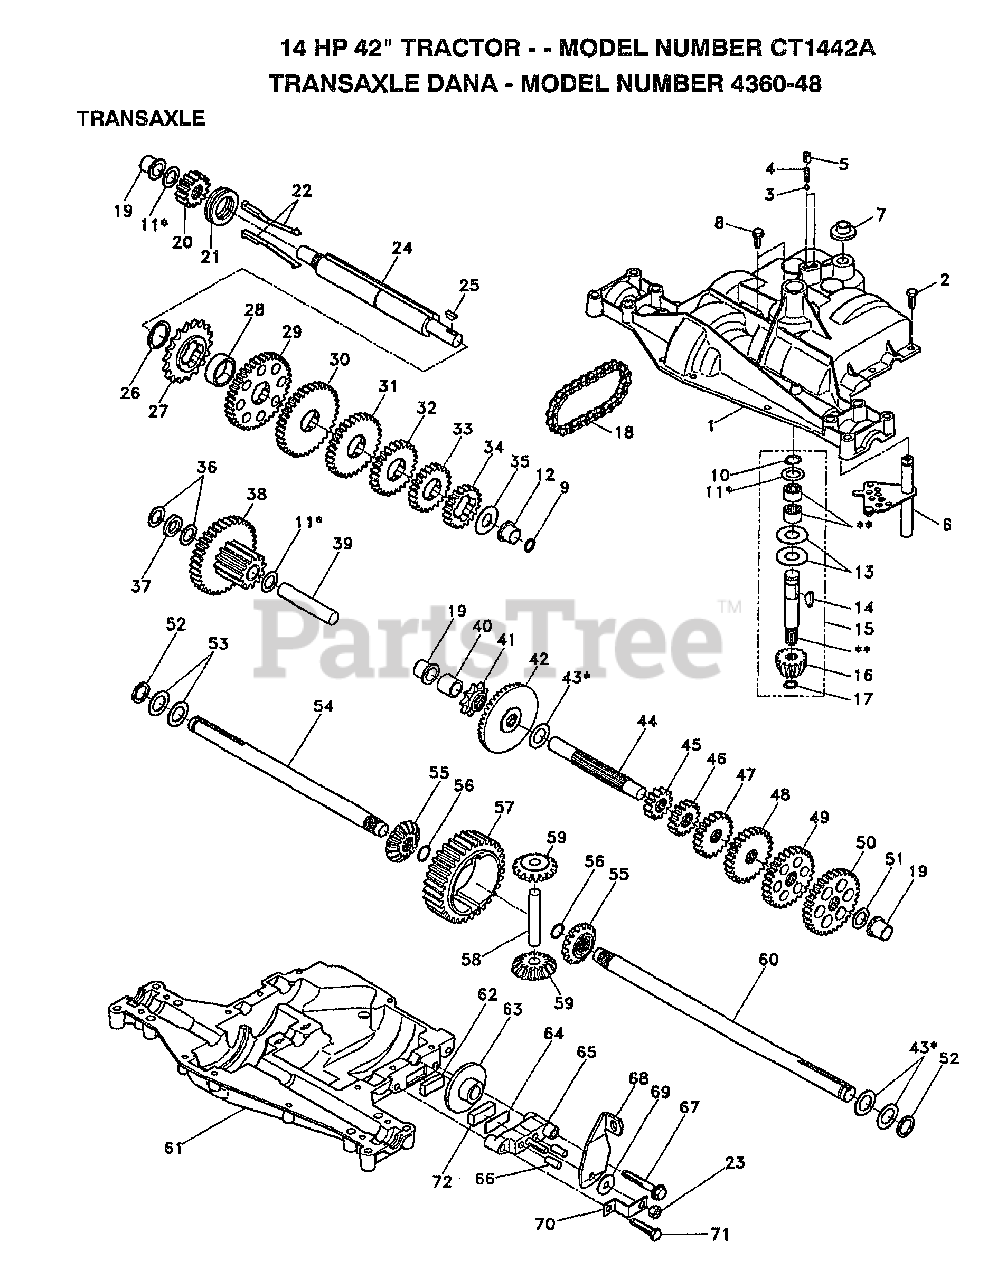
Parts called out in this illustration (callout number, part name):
4	"SPRING, DETENT LT"
5	"SCREW, SET LT"
6	KIT SHIFTER ASM
7	SHIFTER BOOT
8	SCREW TAP W/SEAL
9	SQUARE RING
10	RETAINING RING LT
11	ASM KIT SHIM 4689
12	"FLANGE, BEARING"
13	WASHER T
14	WOODRUFF KEY
15	AS KIT INPUT SHFT
16	PINION 14T T
17	"RING,RETAINING LT"
18	"CHAIN,24 PTCH LT"
19	BEARING.FLNG.5510
20	GEAR SPUR 14T
21	COLLAR CLUTCH
22	ASM KIT CLTCH KEY
23	NUT.LOCK.5/16-24
24	SHAFT INTERM
25	WOODRUFF KEY
26	"RING,RETAINING LT"
27	SPROCKET 18T T
28	SPACER YT
29	KIT.GEAR.12/37TH
32	GEAR 25T LT
33	GEAR SPUR 22 TT
34	SPUR GEAR 19T
35	"WASHER, PLAIN LT"
36	WASHER 025
37	SPACER
38	ASSM GEAR COMB
39	SHAFT IDLER
40	SPACER T
41	SPROCKET 9T LT
43	ASM KIT SHIM
44	SHAFT T
48	"GEAR, SPUR 25T LT"
49	GEAR 28T T
50	"GEAR, SPUR 31T LT"
51	WASHER 060
52	NEOPRENE WASHER
53	WASHER 031
55	GEAR 15T T
56	"RING,RETAINING LT"
58	SHAFT T
59	GEAR 1ST T
62	PUCK T
63	BRAKE DISC. T
64	SPACER LT
66	PIN T
69	WASHER LT
71	"SCREW, TAPPING LT"
72	PUCK T
